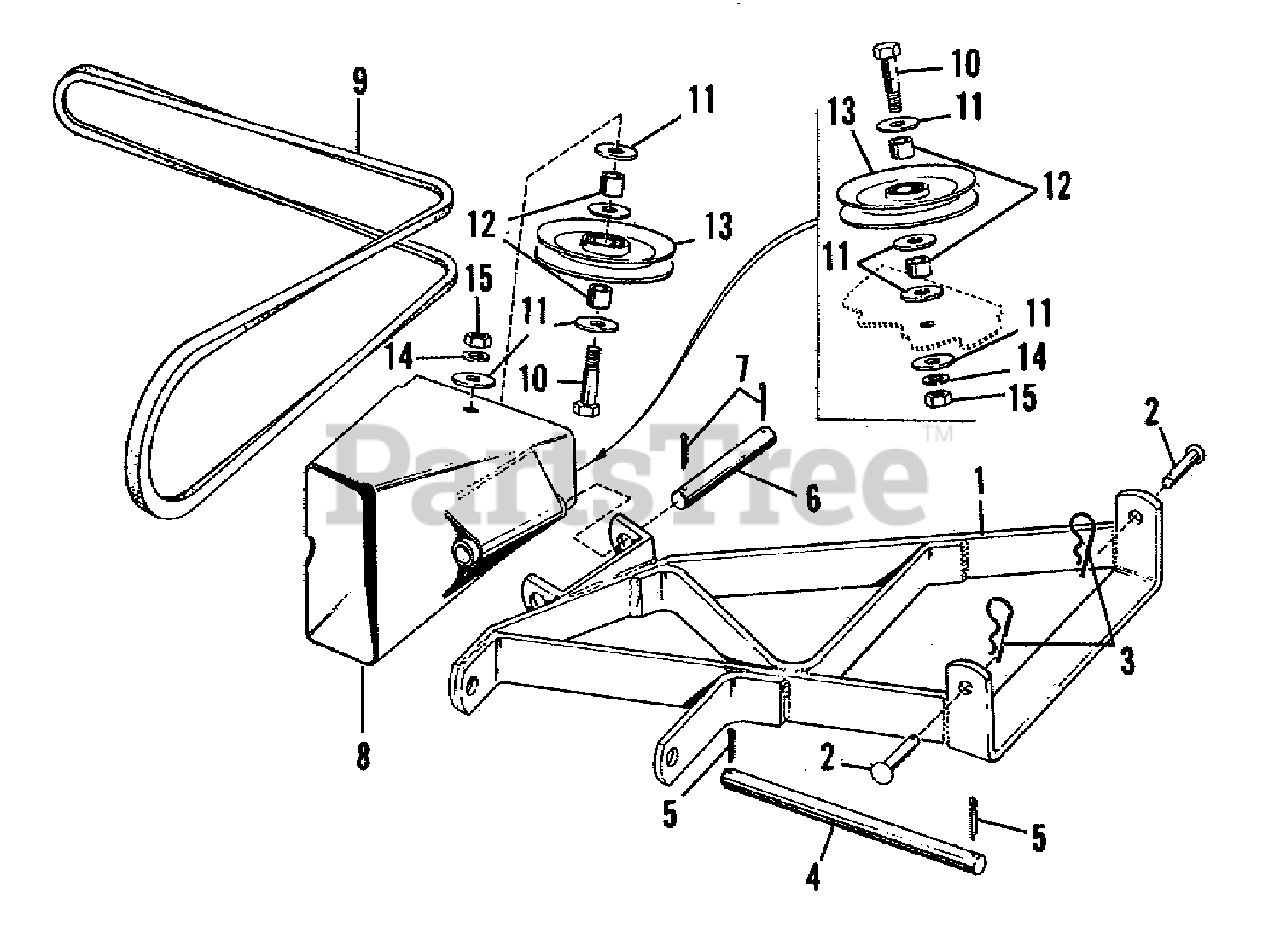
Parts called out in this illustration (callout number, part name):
1	FRAME ASSEMBLY
2	PIN
3	CLIP, Spring
4	SHAFT, Hinge
5	PIN, Cotter, 3/16" x 1"
6	SHAFT, Idler Pulley Bracket
7	PIN, Cotter, 3/16" x 1"
8	GUARD ASSEMBLY, Belt
9	BELT, "V"
10	CAPSCRW, Hex Head, 3/8"-16 x 1-3/4" Lg.
11	WASHER, Plain, 5/16"
13	PULLEY, Idler (w/Ball Bearing)
14	WASHER, Lock, 3/8"
15	NUT, Hex, Full, 3/8"-16
